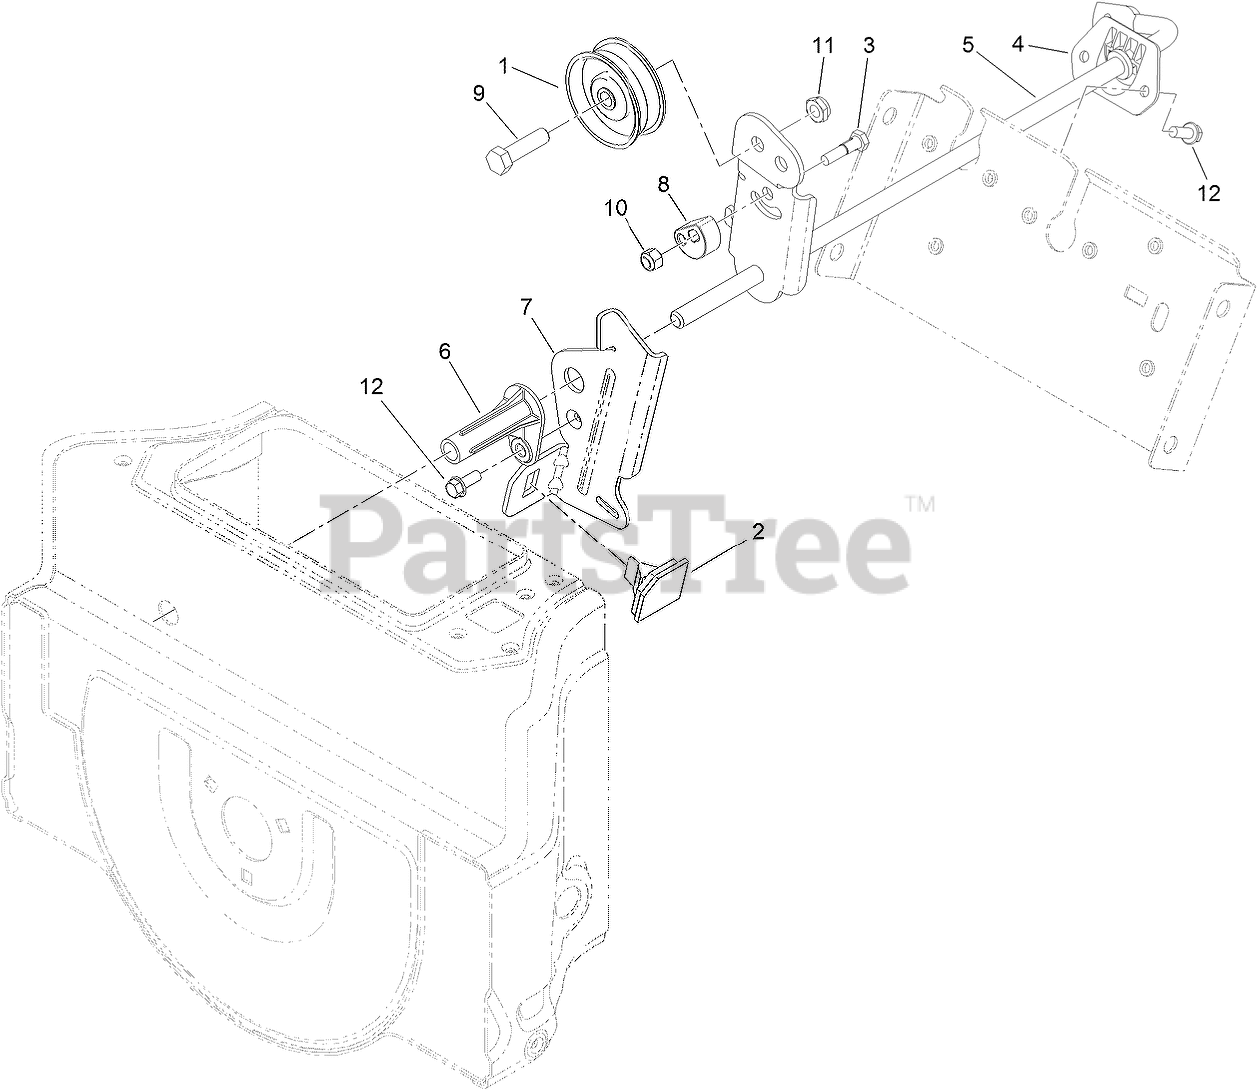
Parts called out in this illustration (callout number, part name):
1	PULLEY-IDLER
2	PAD-BRAKE
3	BOLT-PIVOT, ECCENTRIC
4	BUSHING-ROD, CLUTCH
5	IMPELLER CLUTCH ASM
6	PIVOT-BRAKE, IMPELLER
7	ARM-BRAKE, IMPELLER
8	ECCENTRIC-BRAKE, IMPELLER
9	SCREW-HH
10	NUT-LOCK, NI
11	NUT-LOCK, NI
12	SCREW-HWH
